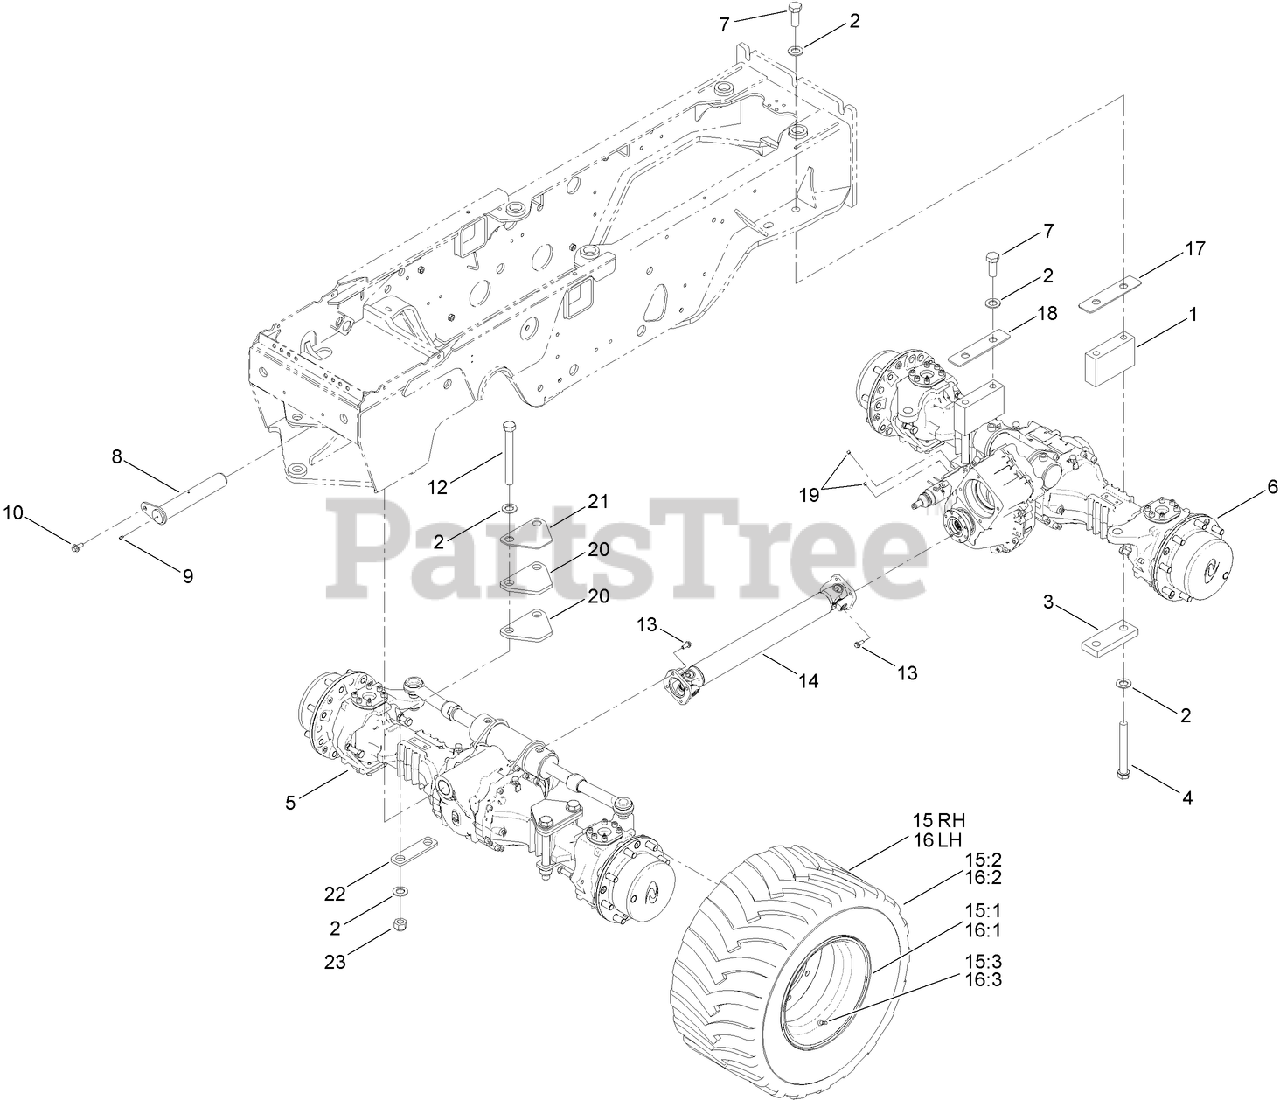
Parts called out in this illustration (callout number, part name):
1	SPACER-AXLE
3	BAR-CLAMP
4	SCREW-CAP
5	FRONT AXLE ASM
6	REAR AXLE ASM
9	FITTING-GREASE
10	SCREW-HHF
13	SCREW-HHF
14	FRONT AXLE DRIVE SHAFT ASM
15	RH WHEEL AND TIRE ASM
15:2	TIRE-31 INCH
15:3	STEM-VALVE
16	LH WHEEL AND TIRE ASM
16:2	TIRE-31 INCH
16:3	STEM-VALVE
17	PLATE-SPACER
18	PLATE-SPACER
19	PLUG-PIPE
20	PLATE-PIVOT, STOP (.500)
21	PLATE-PIVOT, STOP (.188)
22	SPACER-PLATE, AXLE (.375)
23	NUT-HEX, NI
